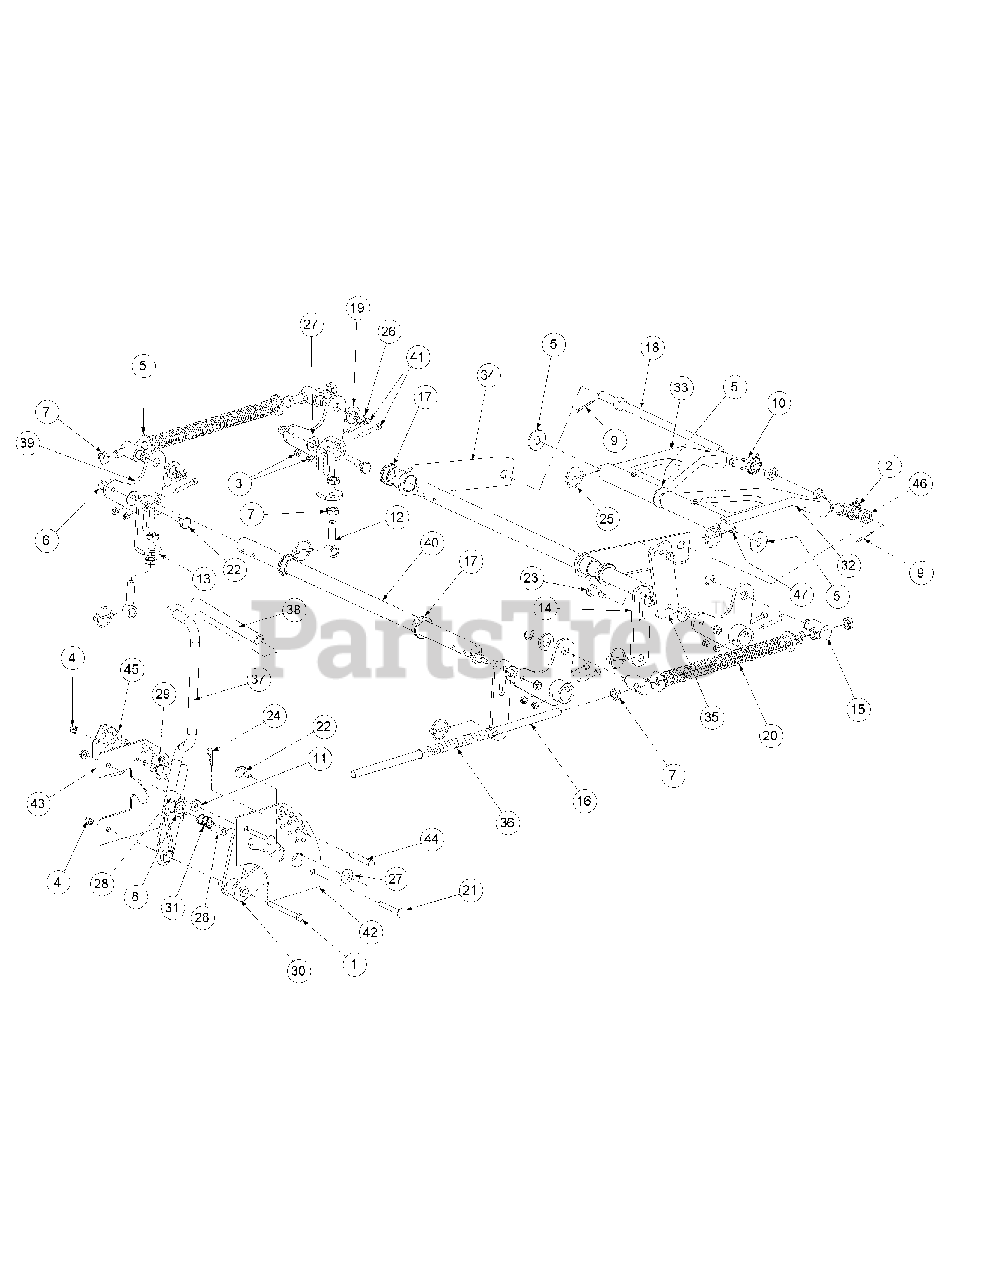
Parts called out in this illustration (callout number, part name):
1	Hex Cap Screw, 3/8-16, 3.75
2	Rod End, Male
3	Nut, 5/16-18, Nylock
4	Nylock Insert Lock Nut, 3/8-16
5	Flat Washer, 5/8
6	Hex Nut, Flange Lock, 3/8-16
7	Jam Nut, 5/8-11
8	Flat Washer, .06, .776, 1.25
9	Cotter Pin, 3/16 x 1-1
10	Jam Nut, 5/8-18
11	Idler Washer
12	Eye Bolt, 5/8ID
13	Eye Bolt Mount Link, 5/8 ID
14	Deck Link
15	Ferule Lift
16	Lift Connector Rod
17	Hex Flange Bearing, 1.25 ID
18	Front Lift Link, Rod Mount
19	Spacer, .812 ID x .268 Lg.
20	Lift Compression Spring
21	Carriage Bolt, 3/8-16, 2.75
22	Shoulder Screw, 0.625 OD x .437 Lg.
23	Shoulder Screw, 0.625 OD x .830 Lg.
24	Cotter Pin, .148 x 3.00
25	Linch Pin, 3/16 Dia.
26	E Clip, 3/4 Dia.
27	Nylon Flat Washer, 5/8
28	Spacer, .39 ID x .63 OD x 1.442
29	Shoulder Screw, .50 OD x 0.27
30	Lift Pivot Assembly
31	Lift Handle Spring
32	Bearing Lift Brace Assembly, Right Hand
33	Bearing Lift Brace Assembly, Left Hand
34	Front Frame Strut Assembly
35	Lift Link Adjustment
36	Hose, 5/8 ID 13/16 OD, 8" LG
37	Lift Handle Assembly
38	Lift Handle Grip
39	Bellecrank Weldment Assembly
40	Deck Lift Shaft
41	Socket Head CapScrew, 5/16-18 x 2
42	Outer Lift Index Plate
43	Inner Lift Index Plate
44	Clevis Pin, .438 Dia. x 2.625 Lg.
45	Decal Height Indicator
46	Spacer, .630 ID x 1.06 OD x .440
47	Lift Link Rod
